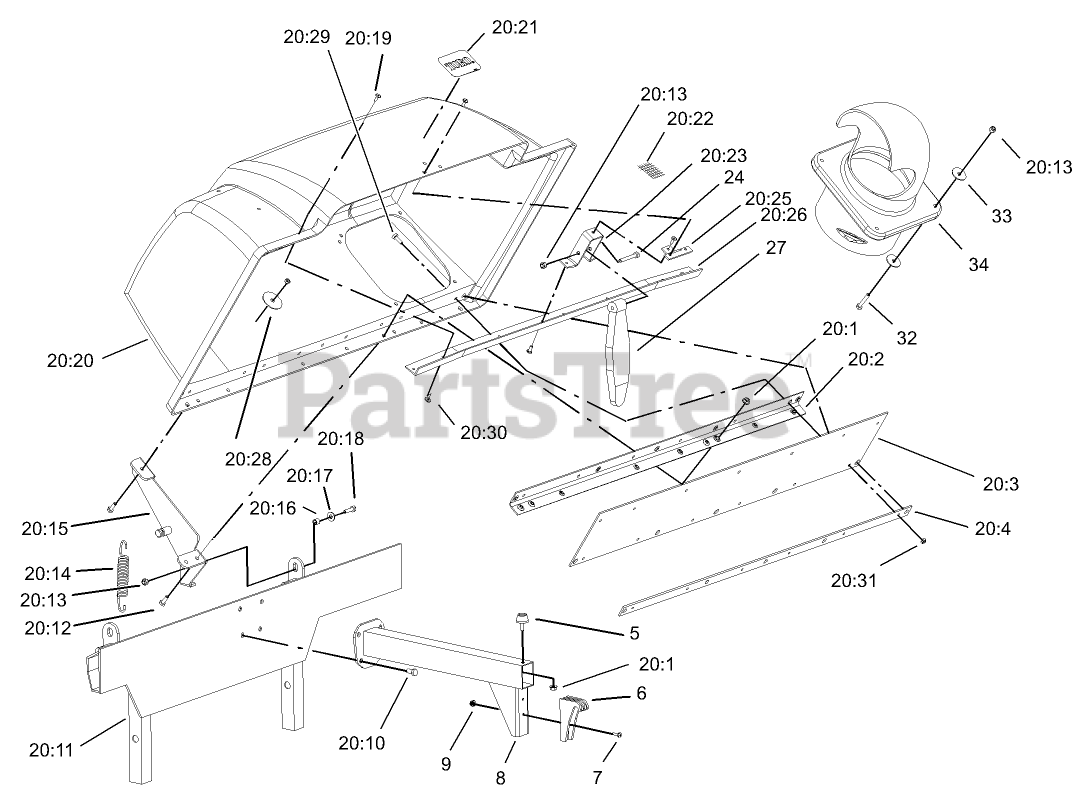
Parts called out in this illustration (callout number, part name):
5	BUMPER
7	SCREW-PPH
8	BAG SUPPORT ASM
9	Nut
20	Hood ASM
20:1	NUT-HF
20:2	STIFFENER-BAGGER, TOP
20:4	PLATE-BACKING
20:10	SCREW-HH
20:11	BAGGER UPRIGHT ASM
20:12	SCREW-HH
20:13	NUT-LOCK, NI
20:14	SPRING-EXTENSION
20:15	HINGE ASM
20:16	SPACER
20:17	WASHER-FLAT
20:18	SCREW-HH
20:19	RIVET-BLIND
20:20	Top-Bagger
20:21	DECAL
20:22	SCREEN-BAGGER
20:23	ANCHOR-LATCH
20:25	REINFORCEMENT-LATCH
20:26	SUPPORT-SCREEN
20:28	WASHER
20:29	SCREW-HEAD, TRUSS
20:30	WASHER-FLAT
20:31	NUT-LOCK, NI
24	SCREW-HH
32	SCREW-HH
33	WASHER-FLAT
34	Tube-Bagger, Upper
